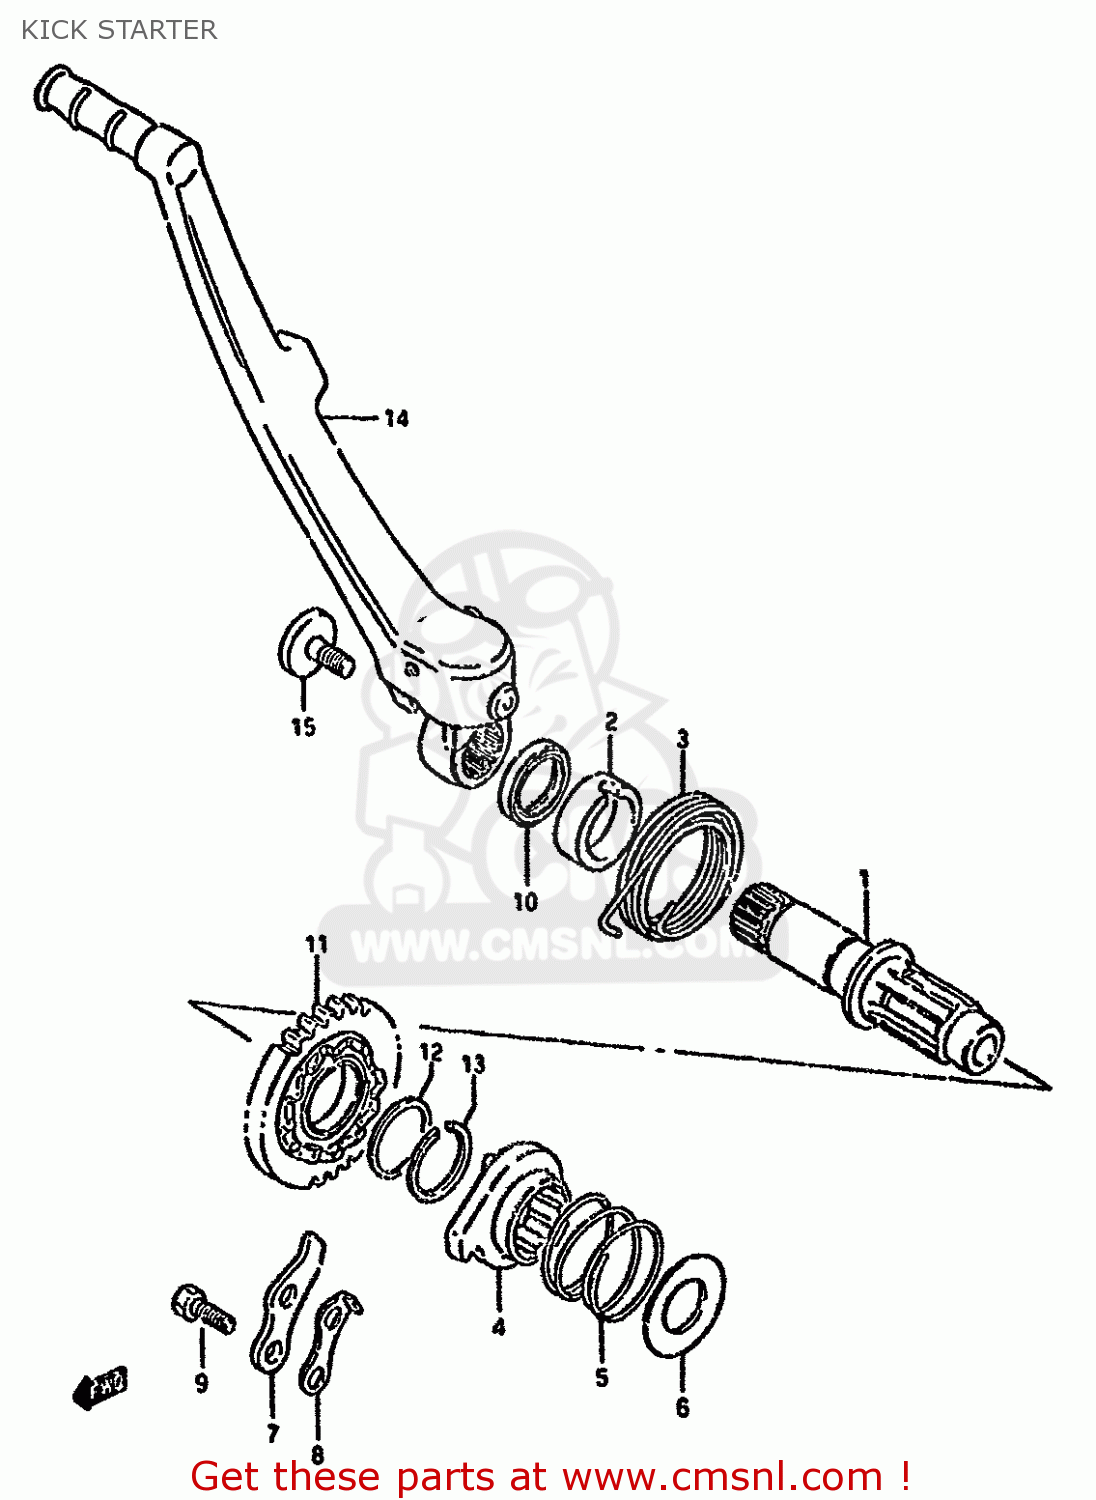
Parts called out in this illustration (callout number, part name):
1	SHAFT,KICK STARTER
2	GUIDE,KICK STARTER SHAFT
3	SPRING
4	STARTER,KICK
5	SPRING
6	WASHER
7	GUIDE,KICK STARTER
8	STOPPER,KICK STARTER
9	BOLT
10	SEAL,OIL(20X27X5)
11	GEAR,KICK STARTER DRIVE(NT:30)
12	SHIM
13	CIRCLIP
14	LEVER ASSEMBLY,KICK STARTER
15	BOLT(8X14)
